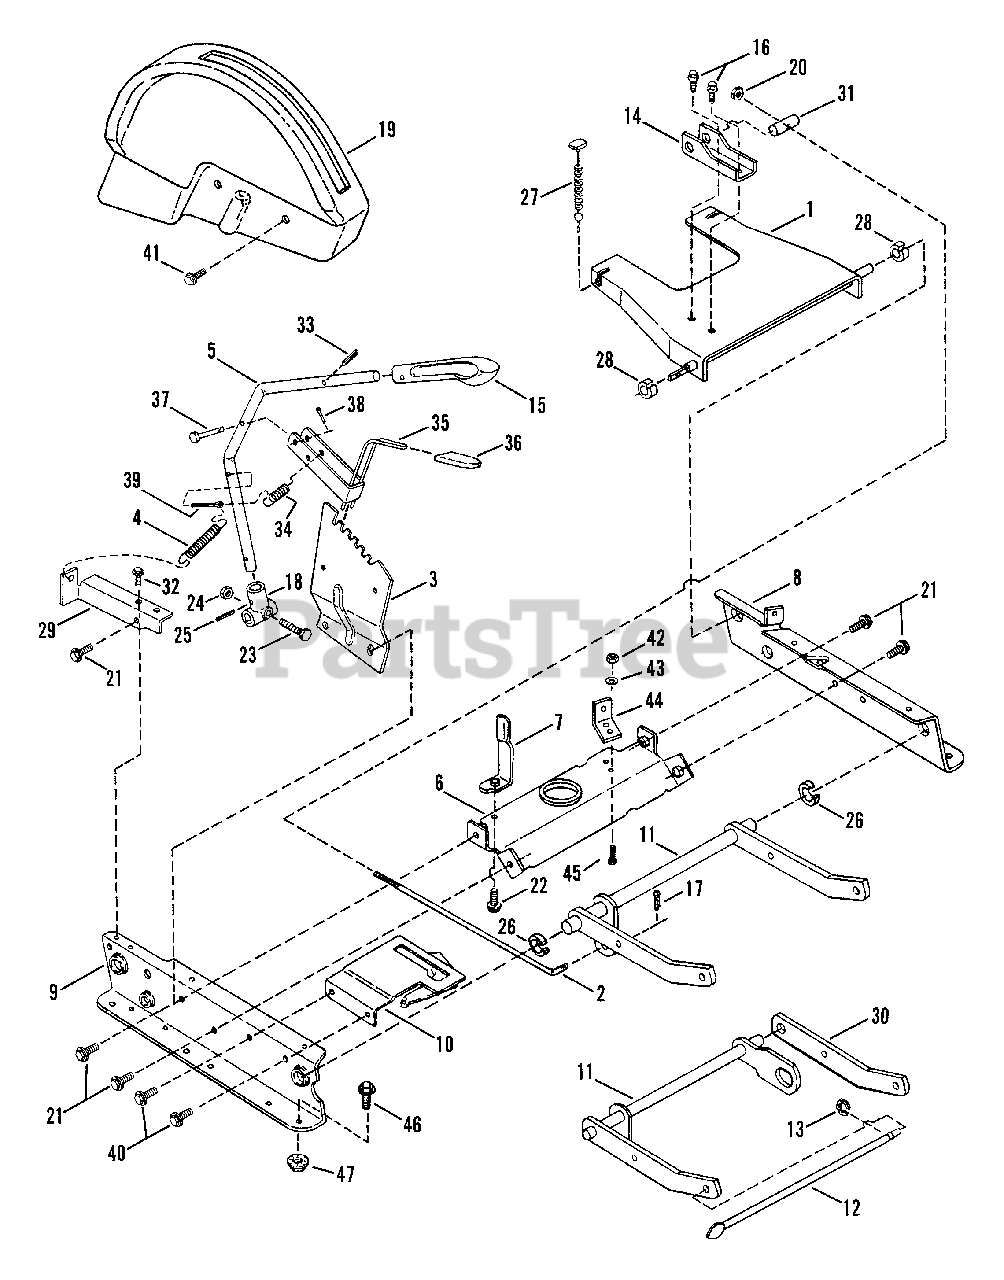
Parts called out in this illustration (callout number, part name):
1	ARM, Rear Lift
2	ROD, Leveling
3	QUADRANT, Lift Lever
4	SPRING, Extension
5	LEVER, Lift
6	BRACE, Top
7	GUIDE, Belt
8	RAIL, Left Hand
9	RAIL, Right Hand
10	ASSEMBLY, Clutch Plate
11	ARM, Front Lift, Non-Adjustable
12	ROD, Support (Front Lift Arm to Front End)
13	RING, 7/16 Retaining
14	ARM, Leveling
15	GRIP, Height Adjustment Lever
16	SCREW, 5/16-18 x 5/8" Self-Tapping (Torx)
17	PIN, 1/8 x 3/4" Cotter
18	HUB, Deck Lift
19	COVER, Height of Cut
20	NUT, 3/8-24 Hex Nyloc
21	SCREW, 3/8-16 x 5/8" Self-Tapping
22	SCREW, 5/16-18 x 5/8" Self-Tapping
23	BOLT, 5/16-24 x 1-5/8" Tapered Axle
24	NUT, 5/16-24 Hex Flange Lock
25	PIN, 3/16 x 1" Roll
26	RING, Red
27	CABLE, Rear Deck 5.0", 7 Furrels
28	RING, White
29	BRACKET, Deck Lift
30	ARM, Front Lift-Left
31	PIVOT, Leveling
32	SCREW, 1/4-20 x 3/8" Self-Tapping
33	PIN, 3/16 x 3/4" Roll
34	SPRING, Latch
35	LATCH
36	GRIP, Lift Latch
37	PIN, Clevis
38	PIN,1/16 x 3/4" Cotter
39	PIN, 3/16 x 1 1/2" Cotter
40	SCREW, 5/16-18 x 1/2" Self-Tapping
41	SCREW, 1/4-20 x 5/8" Hex Head, Self-Tapping
42	NUT, 5/16-24 Hex 2
43	WASHER, 5/16 Internal Tooth Lock
44	ANCHOR
45	SCREW, 5/16-24 x 3/4" Hex Head Cap
46	BOLT, 5/16-18 x 5/8" Hex Flange Lock
47	NUT, 5/16-18 Hex Flange Lock
